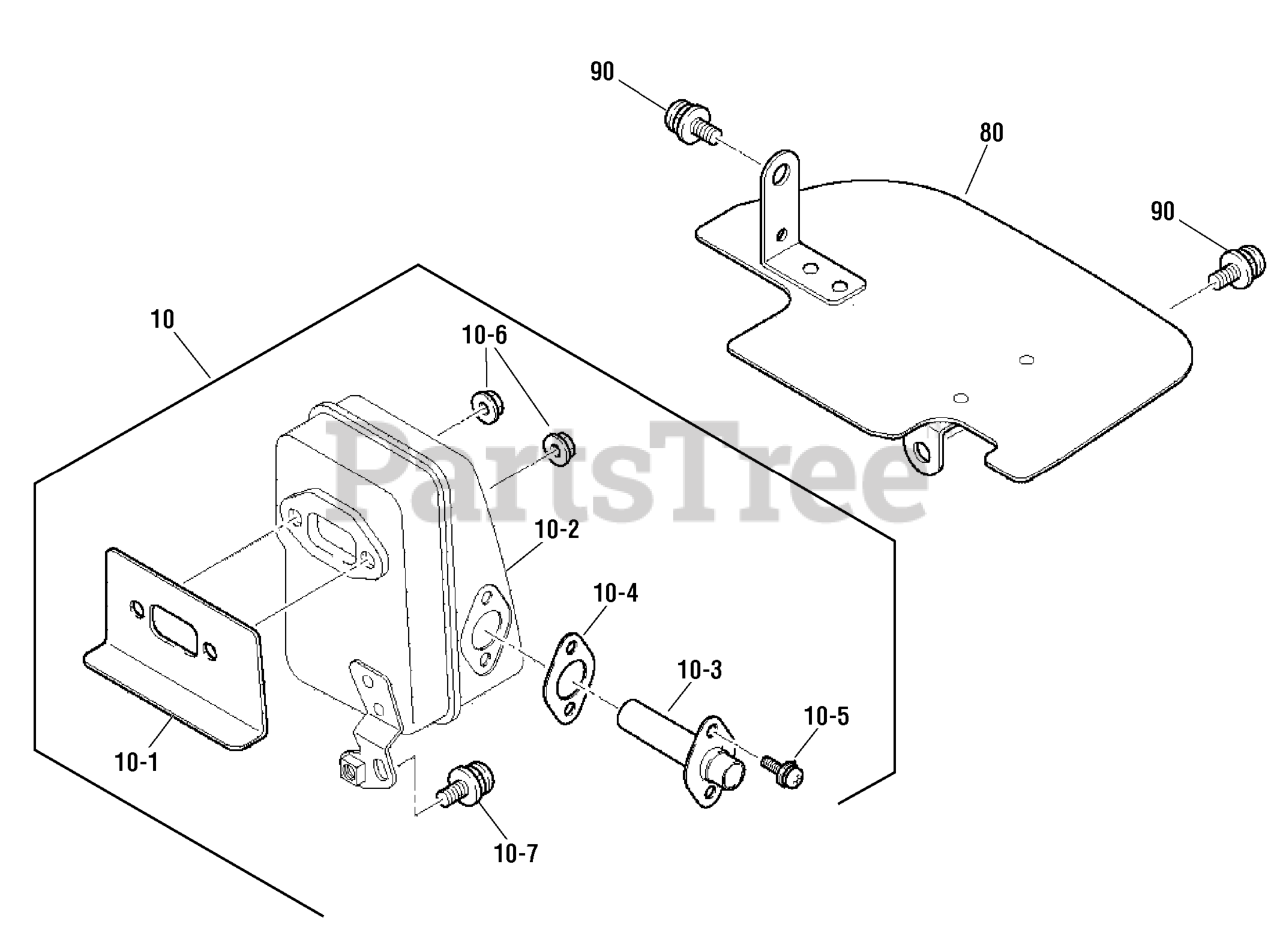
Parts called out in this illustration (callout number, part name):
10	MUFFLER & GASKET KIT
10-1	GASKET, Muffler
10-2	MUFFLER
10-3	TAIL PIPE
10-4	GASKET
10-5	SCREW & WASHER
10-6	NUT, Flange
10-7	SCREW & WASHER
80	GASKET
90	SCREW & WASHER
